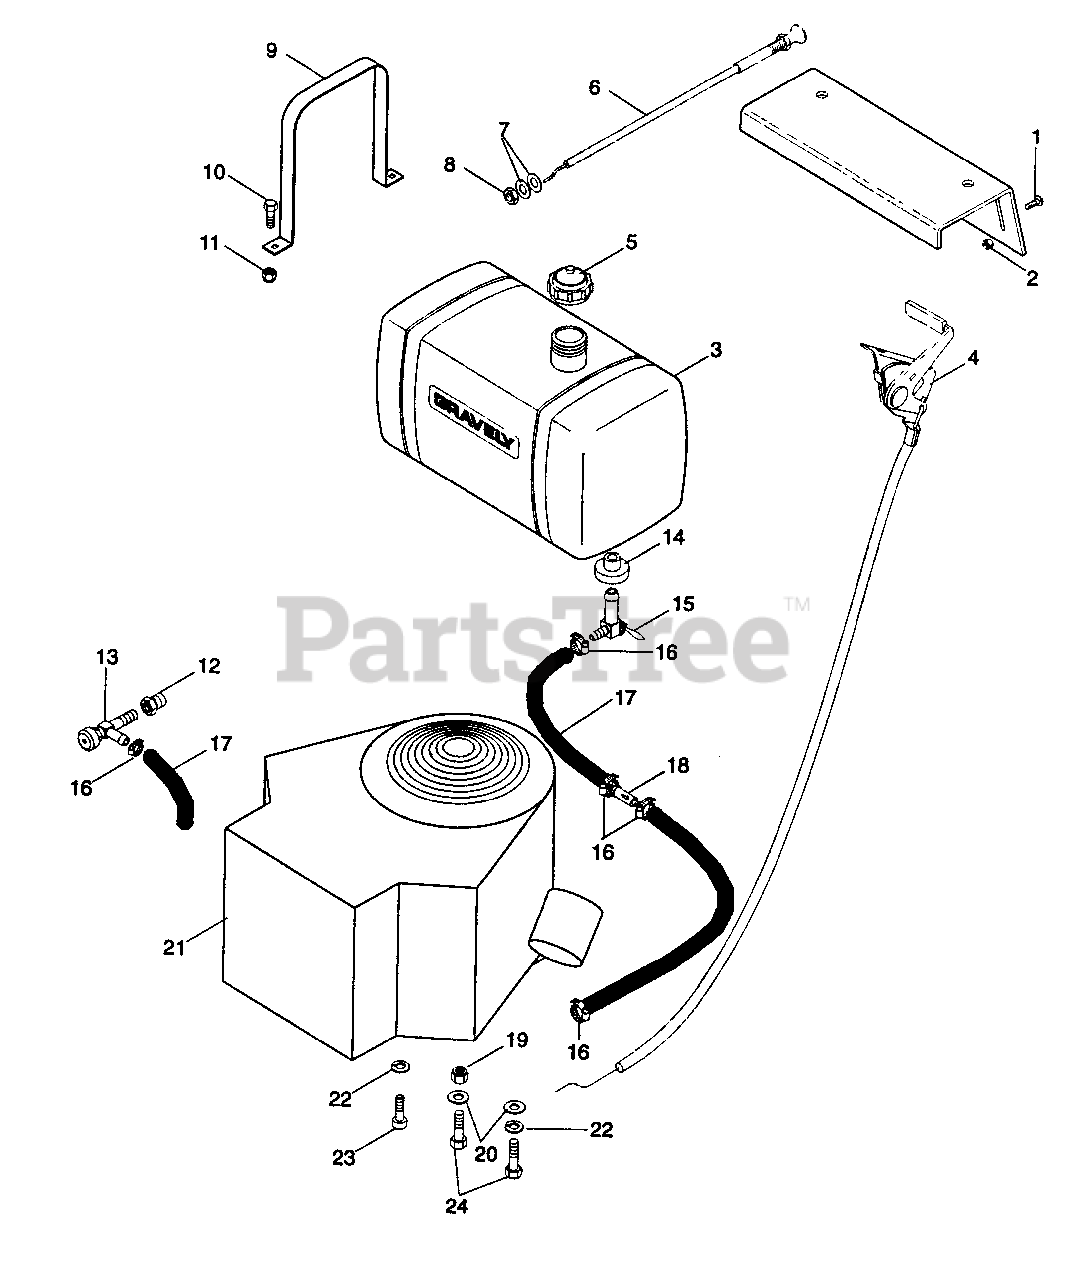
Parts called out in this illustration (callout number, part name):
1	Screw-Machine 10-32 x .50
2	Nut-Locking 10-32 Hex w/Insrt
3	Tank, Fuel, Gravely PRO
4	Assembly, Throttle Control/Cable (14 HP)
5	Cap, Fuel Tank
6	Control, Choke
7	Washer-Flat-Steel .406 x .812 x .065
8	Nut-Jam .375-24
9	Strap, Fuel Tank
10	Bolt-Hex .25-20 x .63
11	Nut-Locking-Nylon .250-20 Grade 2
12	Adapter, Oil Drain (14 HP)
13	Cock, Oil Drain
14	Bushing, Flange .375 x 1.06 x .625
15	Valve, Ball Shut-Off
16	Hose Clamp
17	Gas Line, Bulk
18	Filter, Fuel
19	Nut-Locking-Nylon .312-18 Grade 2
20	Washer-Flat-Steel .344 x .688 x .065
21	Engine, 14 HP Kawasaki OHV
22	Washer-Lock .313 x .078
23	Screw-Socket Head M8 x 1.25 x 20mm
24	Bolt-Hex. .31-18 x 1.50 Grade 5
